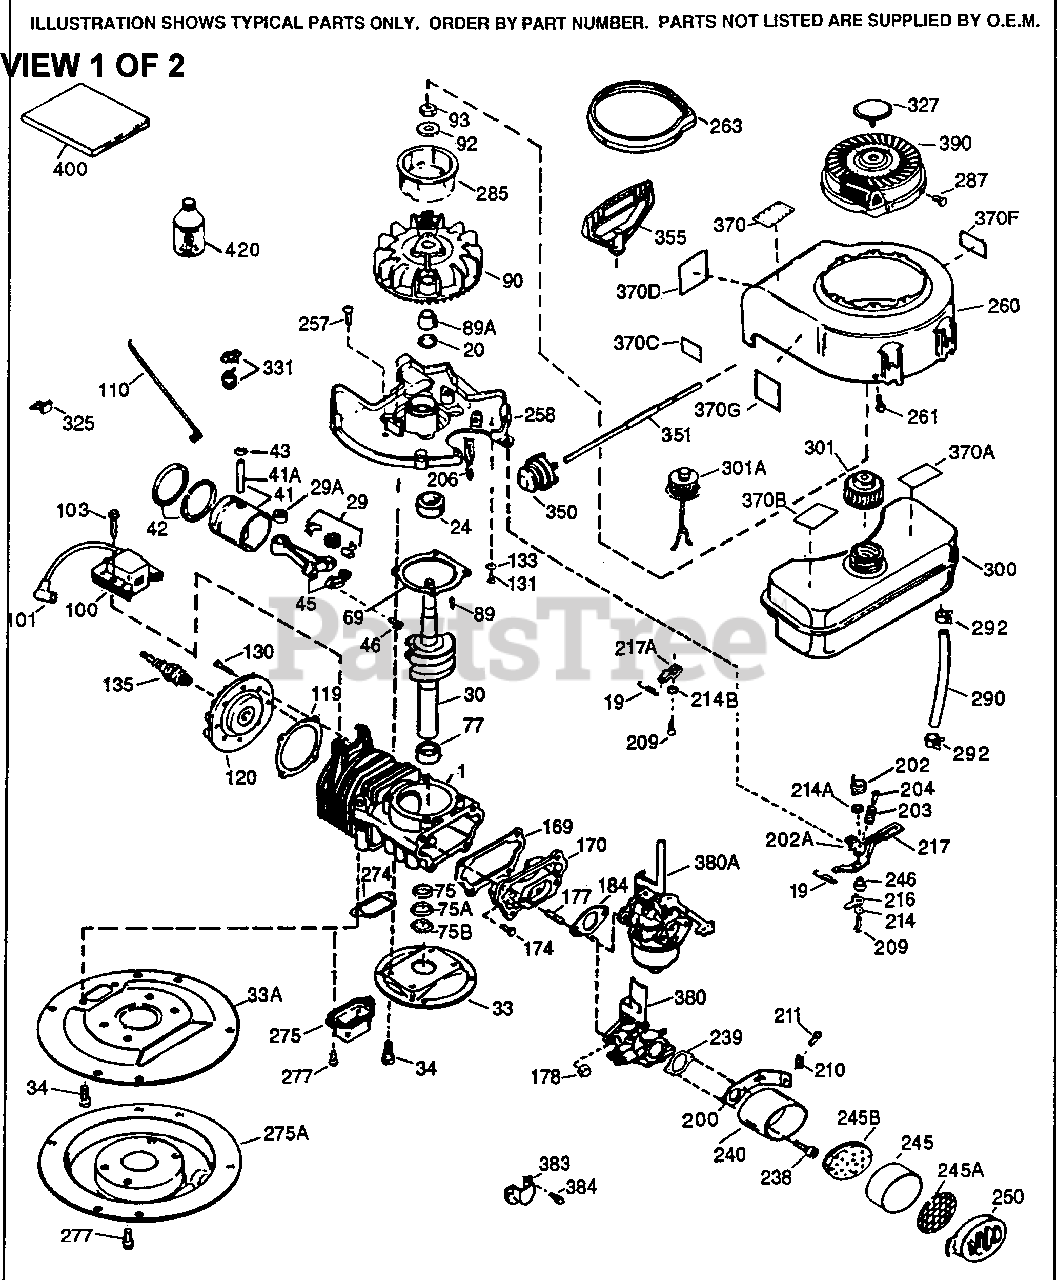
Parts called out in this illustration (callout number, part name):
1	"Cylinder (Incl. 28, 28A, 28B & 77)
19	Extension Spring
24	Ball Bearing
27	Oil Seal
28	Oil Seal
28A	Oil Seal Retainer
28B	Oil Seal Retainer Spring
29	Needle Bearing & Liner Set 37 Needle s
29A	Cartridge Bearing
30	Crankshaft
33	Adapter Plate
34	Screw, 5/16-18 x 1/2"
41	Piston & Pin Ass'y. (Incl. 43)
41A	Piston Pin
42	Ring Set
43	Piston Pin Retaining Ring
45	Connecting Rod Assy. Incl. 29, 29A & 46
46	Connecting Rod Bolt
69	* Cylinder Cover Gasket
77	Cartridge Bearing
89	Flywheel Key (also available in Packa ged Part #740007B)
92	Belleville Washer
93	Flywheel Nut
101	Spark Plug Cover
110	Ground Wire
119	* Cylinder Head Gasket
120	Cylinder Head
130	Screw, Torx T-30, 1/4-20 x 3/4"
135	Resistor Spark Plug - RJ17LM
169	* Cover Plate Gasket
170	Reed & Cover Plate (Incl. 178)
174	Screw, Torx T-25, 10-24 x 1/2"
178	Nut & Lock Washer 1/4-28
184	* Carburetor Gasket
203	Compression Spring
204	Screw, 5-40 x 7/16"
209	Screw, Torx T-25, 10-24 x 7/8"
216	R.P.M. Adjusting Lever
217	Control Lever
238	Screw, Torx T-25, 10-32 x 5/8"
239	Air Cleaner Gasket
240	Air Cleaner Body
245	Air Filter
245A	Air Filter
245B	Air Filter
250	Air Cleaner Cover
257	Screw, Torx T-30, 1/4-20 x 5/8"
258	Blower Housing Base
261	Screw, 1/4-20 x 7/16"
274	Exhaust Gasket (.031" thick)
285	Starter Cup
290	Fuel Line (8.62")
292	Fuel Line Clamp
300	Fuel Tank (Incl. 301)
301A	Fuel Cap
331	Toggle Switch
370A	Warning Decal
370B	Fuel Mix Decal
370D	Instruction Decal
380	Carburetor (Incl. 184) (Refer to Divi sion 5, Section A, page A7-14 or Fich e 23B, Grid F-7 for breakdown)
400	* Gasket Set (Incl. items marked *)
422	2-Cycle Oil with Fuel Stabilizer - 8 oz.
